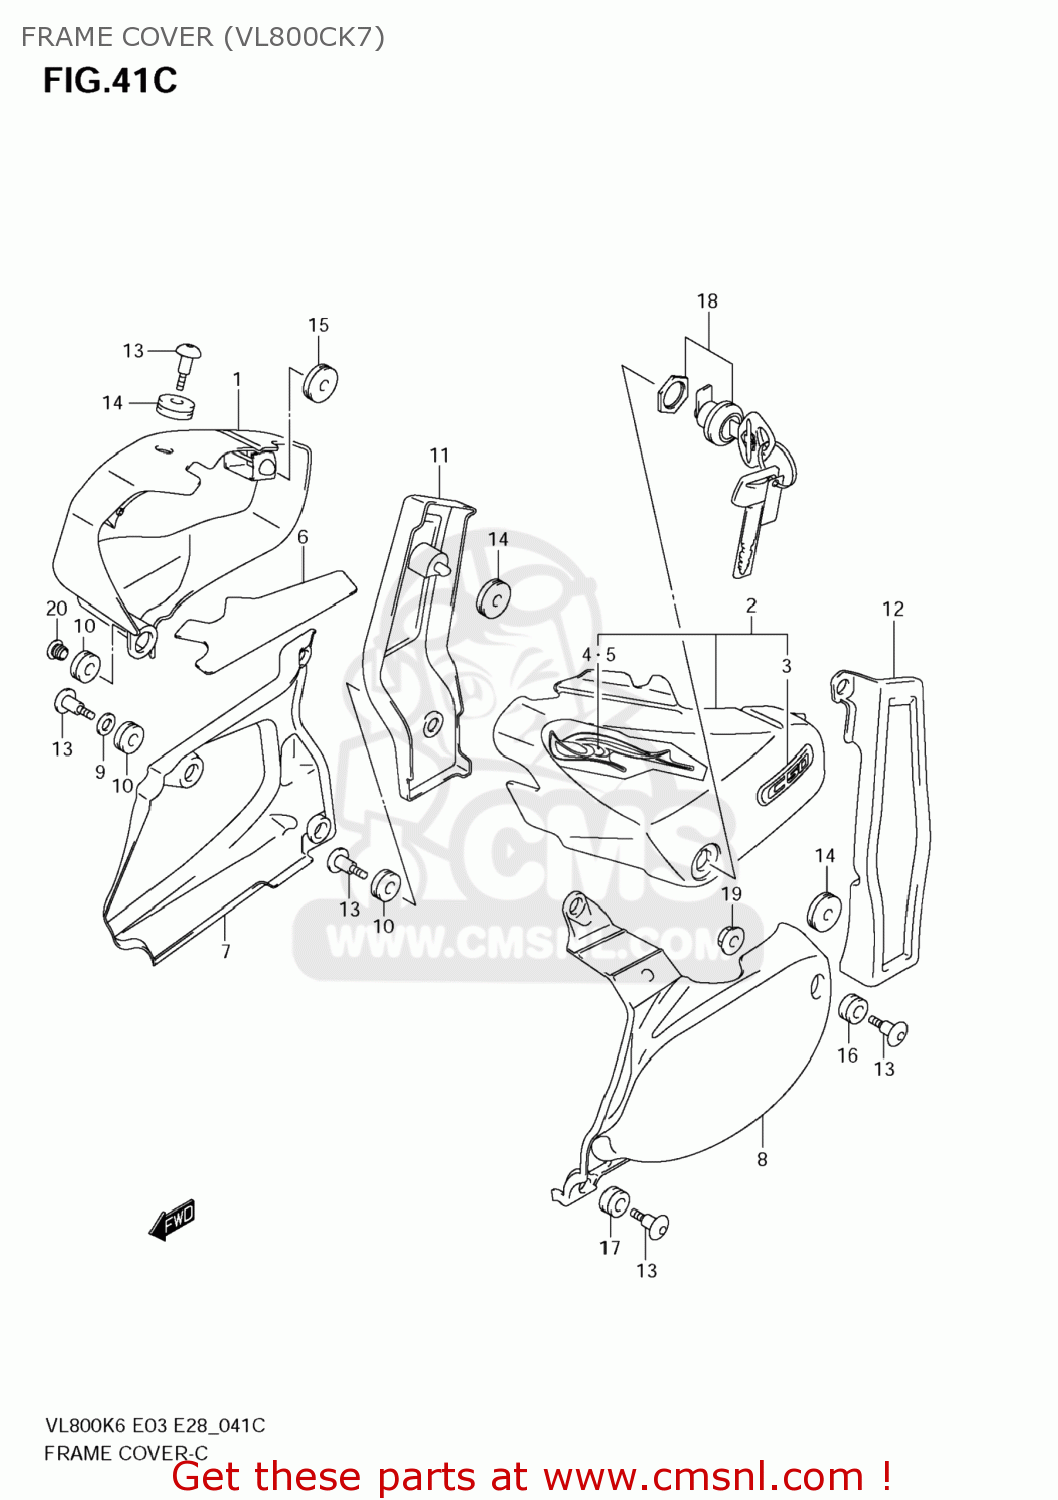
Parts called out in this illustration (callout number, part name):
1	COVER,SIDE,R(GRAY)
2	COVER,SIDE,L(GRAY)
3	EMBLEM,C50
4	TAPE, RH
5	TAPE,FRAME COVER,L
6	SHIELD,FRAME COVER
7	COVER,SIDE LWR,R
8	COVER,SIDE LWR,L
9	WASHER(10.5X20X2.3)
10	CUSHION
11	COVER,SIDE RR,R
12	COVER,SIDE RR,L
13	SCREW(6X20)
14	CUSHION
15	CUSHION
16	CUSHION
17	CUSHION
18	LOCK SET,COVER
19	NUT
20	CAP(OD:14)
